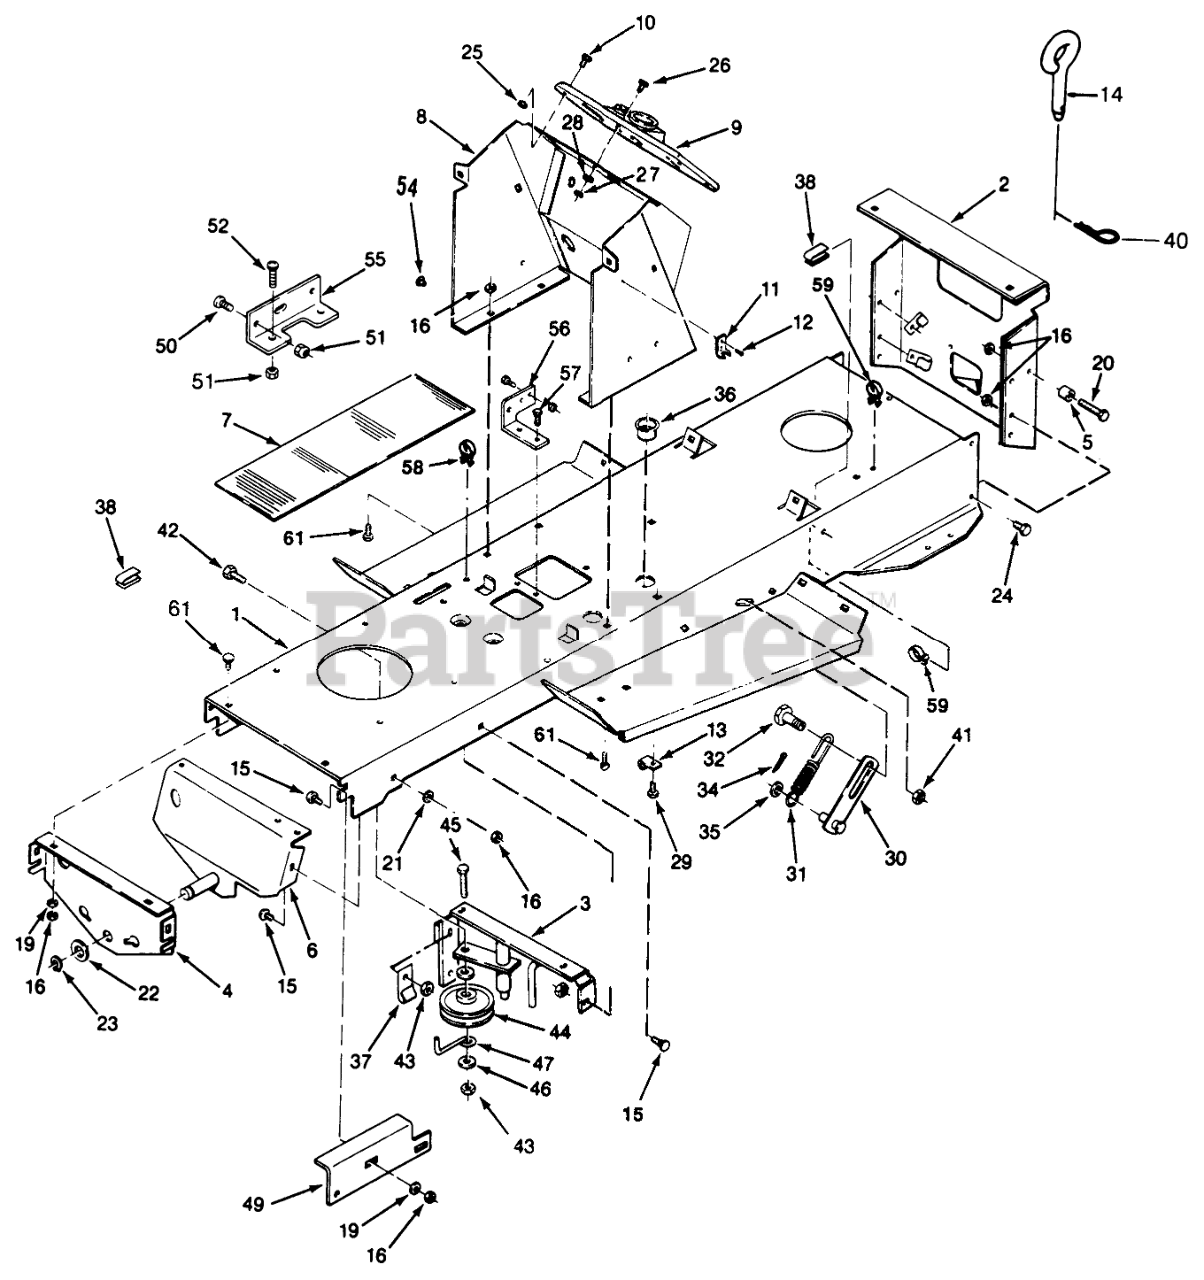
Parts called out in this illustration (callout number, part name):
1	FRAME R
2	PLATE-DRAWBAR R
3	ASS'Y-FRAME SUPPO R
4	PLATE SUPT - AXLE R
5	Spacer
6	ASS'Y-AXLE SPT RE R
7	PAD-FOOTREST
8	WLDMT-HOODSTAND B
9	CONSOLE
10	SCREW #10X.62 PHCR
11	KEEPER-LATCH
12	POPRIVET 1/8X 1/8 BK
13	J-CLIP
14	PIN-TOOL
15	BOLT-CARR
16	NUT-LOCK, NI
19	WASHER-PLAIN
20	SCREW-HH
21	WASHER-LOCK, INTERNAL
22	WASHER
23	RING-RETAINING
24	SCREW-HH
25	Nut
26	Screw
27	NUT-HEX
28	WASHER-LOCK
29	SCREW-HH
30	ASSY LINK B
31	SPRING
32	CAM-ADJUST
34	PIN-COTTER
35	WASHER
36	BUSHING-NYLON 1.093
37	CLIP
38	RETAINER
40	Hairpin Cotter
41	NUT-HEX, JAM
42	SCREW-HH
43	NUT-LOCK, NI
44	IDLER PULLEY R
45	SCREW-HH
46	WASHER-FLAT
47	RETAINER BELT R
49	BRACKET R.H. R
50	Screw
51	Nut
52	Screw
54	PLUG-NYLON .250
55	BRKT-FUSE HOLDER B
56	BRKT-SWITCH R
57	Screw-Machine
58	CLIP-SNAP IN
59	CLIP-SNAP IN
61	BOLT-CARR
